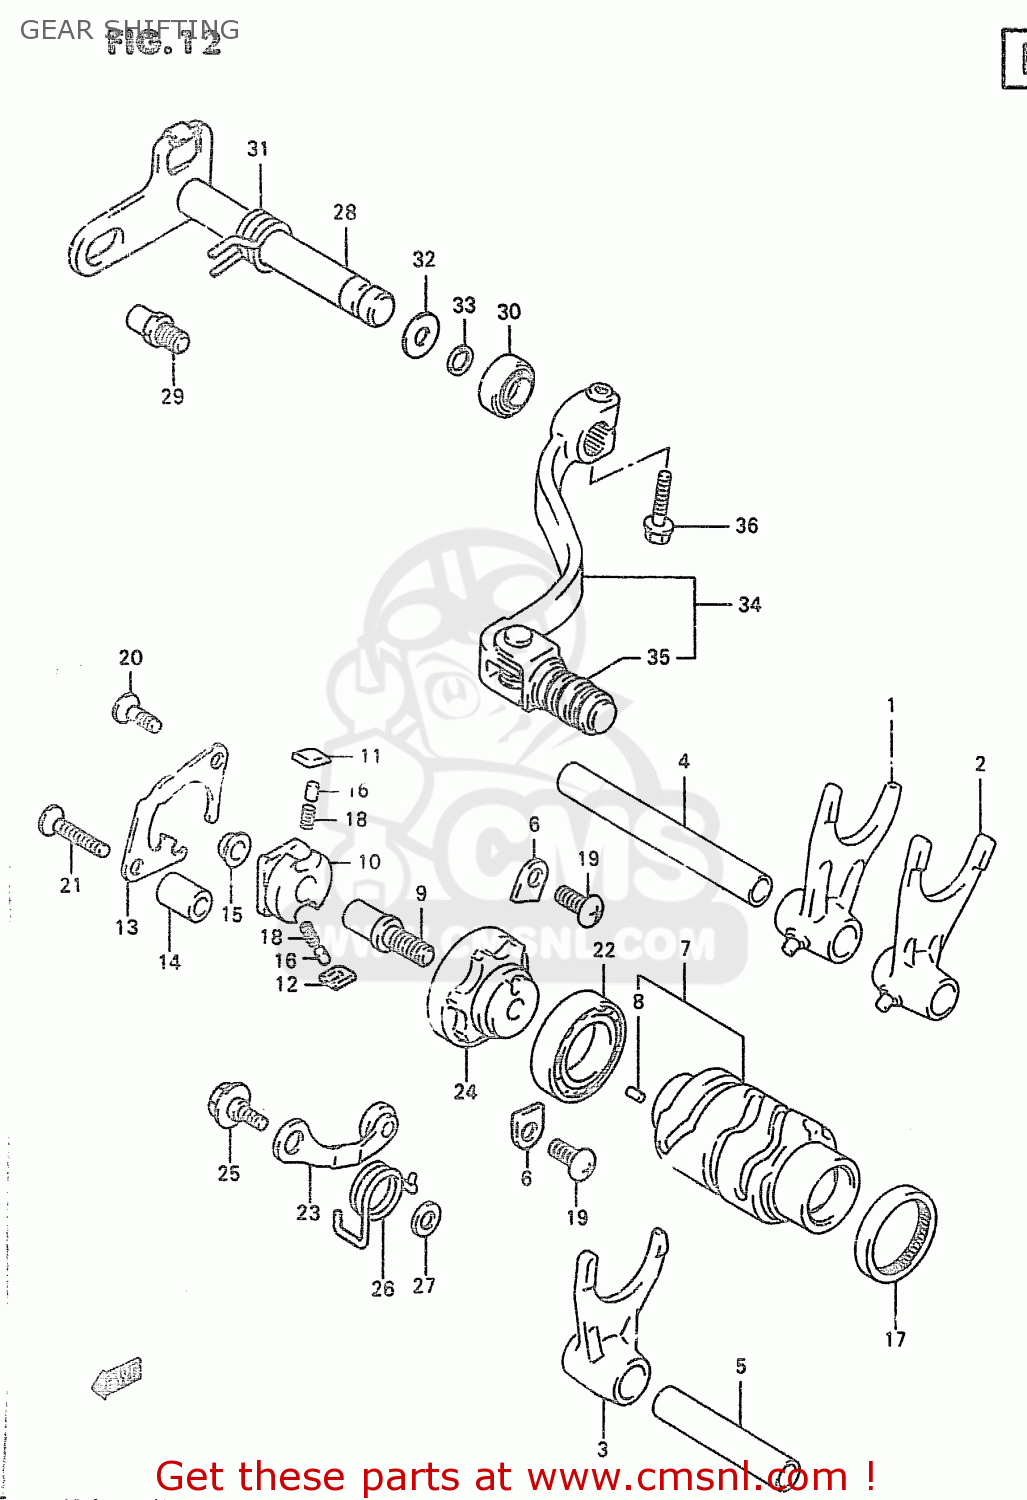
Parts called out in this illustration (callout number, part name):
1	FORK,GEAR SHIFT NO.1
2	FORK,GEAR SHIFT NO.2
3	FORK,GEAR SHIFT NO.3
4	SHAFT,GEAR SHIFT FORK
5	SHAFT,GEAR SHIFT FORK
6	RETAINER
7	CAM,GEAR SHIFT
8	PIN
9	PIN,SHIFT CAM DRIVEN GEAR
10	SHIFTER,GEAR SHIFT CAM
11	PAWL,GEAR SHIFT NO.1
12	PAWL,GEAR SHIFT NO.2
13	LIFTER,GEAR SHIFT PAWL
14	SPACER(6.2X12X18)
15	SPACER(7X10X5)
16	PIN(5X8)
17	BEARING(33X38X8)
18	SPRING
19	SCREW
20	SCREW
21	SCREW
22	BEARING
23	STOPPER,SHIFT CAM
24	PLATE,SHIFT CAM STOPPER
25	BOLT(6X14.3)
26	SPRING
27	WASHER
28	SHAFT,GEAR SHIFT
29	STOPPER,SHIFT ARM
30	SEAL,OIL(14X22X6)
31	SPRING
32	WASHER
33	CIRCLIP
34	LEVER ASSEMBLY,GEAR SHIFTING
35	RUBBER,GEAR SHIFT PEDAL
36	SCREW
